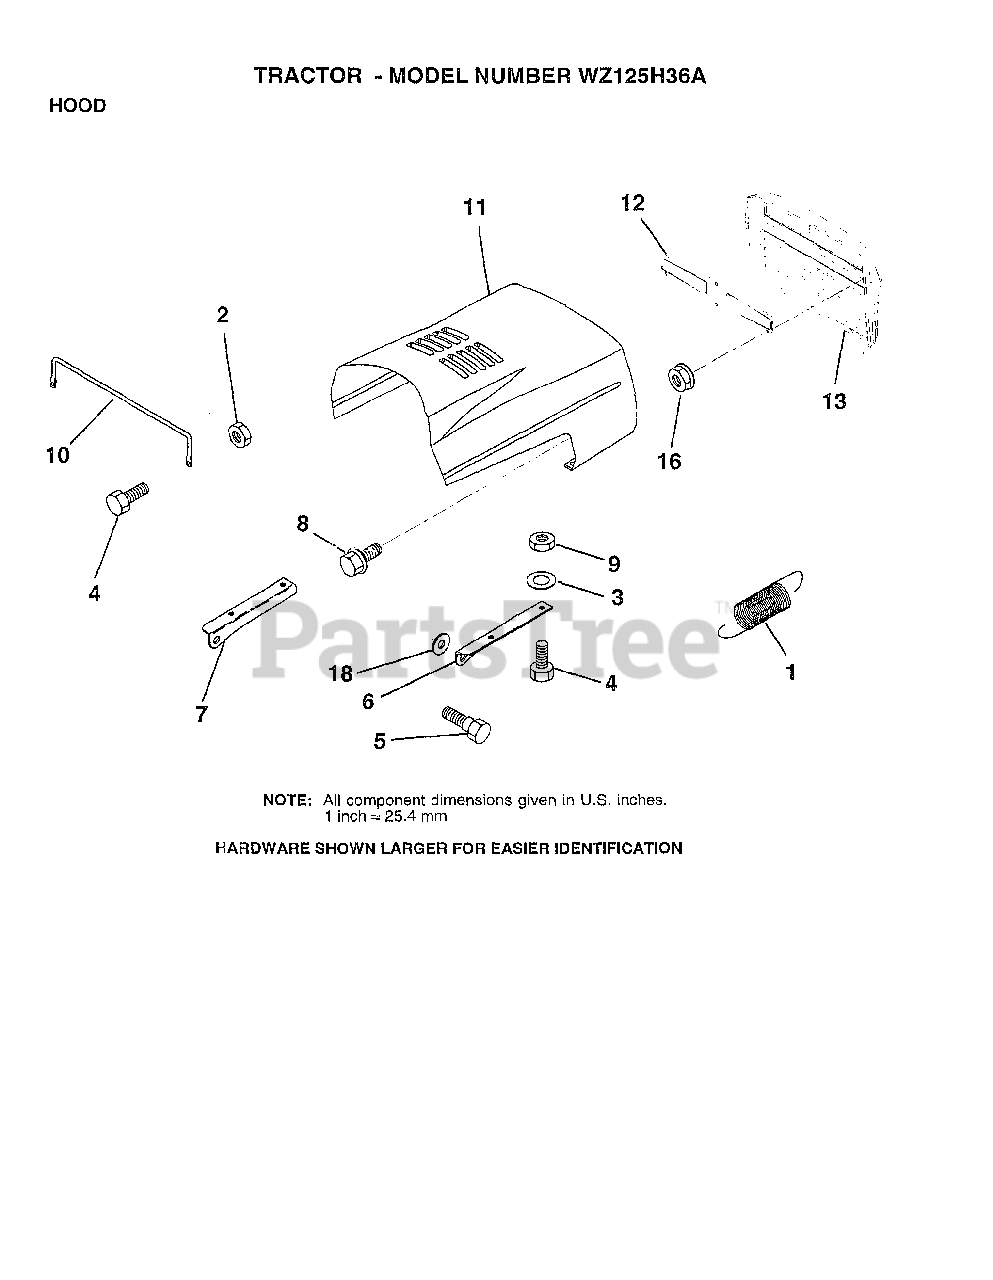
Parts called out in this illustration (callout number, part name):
1	EXT SPRING
2	NUT
3	WASHER
5	BOLT.SHLD.5/16-18
6	BRKT HOOD RH
7	BRKT HOOD LH
8	SCREW SLTD HXHD
9	NUT
10	"BRACE,HOOD"
11	HOOD
13	GRILL (BLACK)
16	NUT
18	WASHER
